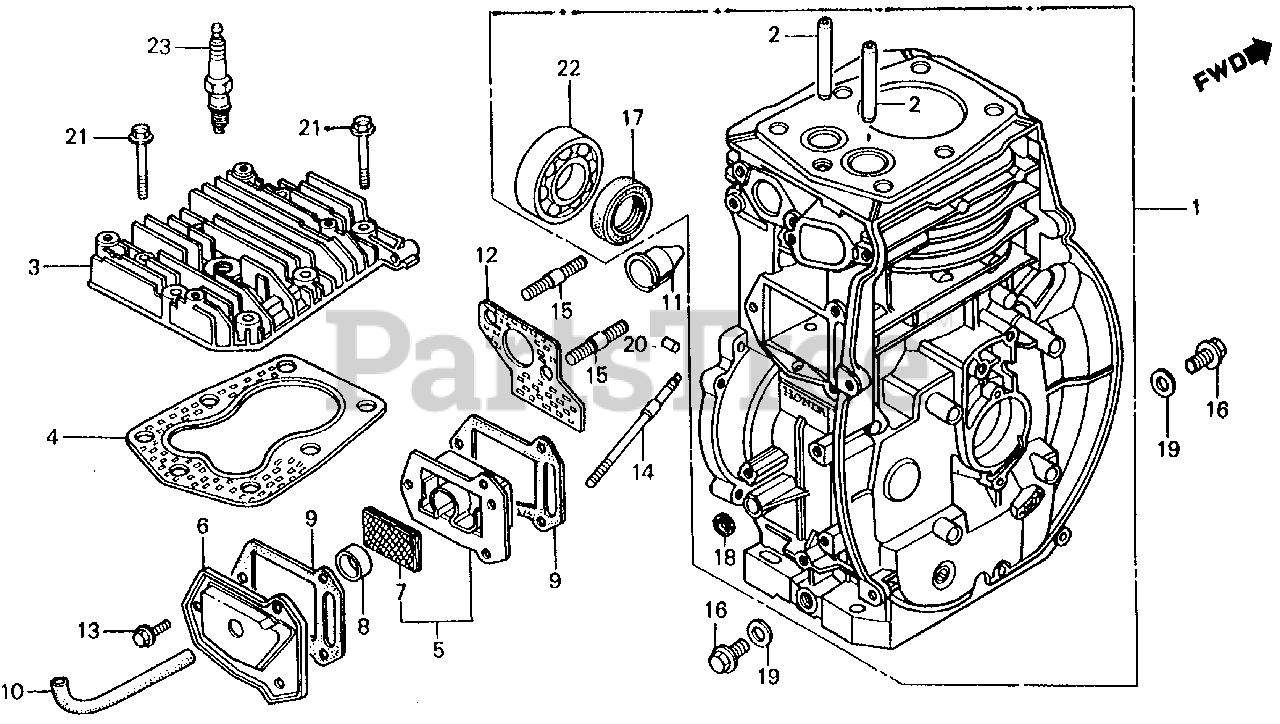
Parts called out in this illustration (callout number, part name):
1	CYLINDER ASSY.
2	GUIDE, VALVE (OS)
3	CYLINDER HEAD (NOT AVAILABLE)
4	GASKET, CYLINDER HEAD
5	CASE, BREATHER
6	COVER, TAPPET ROOM
7	FILTER, BREATHER
8	SEAL, BREATHER
9	GASKET, TAPPET COVER
10	TUBE, BREATHER (NOT AVAILABLE)
11	LINER, EX. PORT
12	GASKET, MUFFLER
13	BOLT, FLANGE (6X12) (CT200)
14	BOLT, STUD (6X89)
15	BOLT, STUD (8X35)
16	BOLT, DRAIN PLUG
17	OIL SEAL (25X41X6)
18	OIL SEAL (6X11X4)
19	WASHER, DRAIN PLUG (12MM)
20	PIN A, DOWEL (8X14)
21	BOLT, FLANGE (8X45)
22	BEARING, RADIAL BALL (6205)
23	SPARK PLUG (BPR-4HS-10) (NGK)
23	SPARK PLUG (BPR4HS-10) (NGK)
23	SPARK PLUG (W14FPR-UL10)
